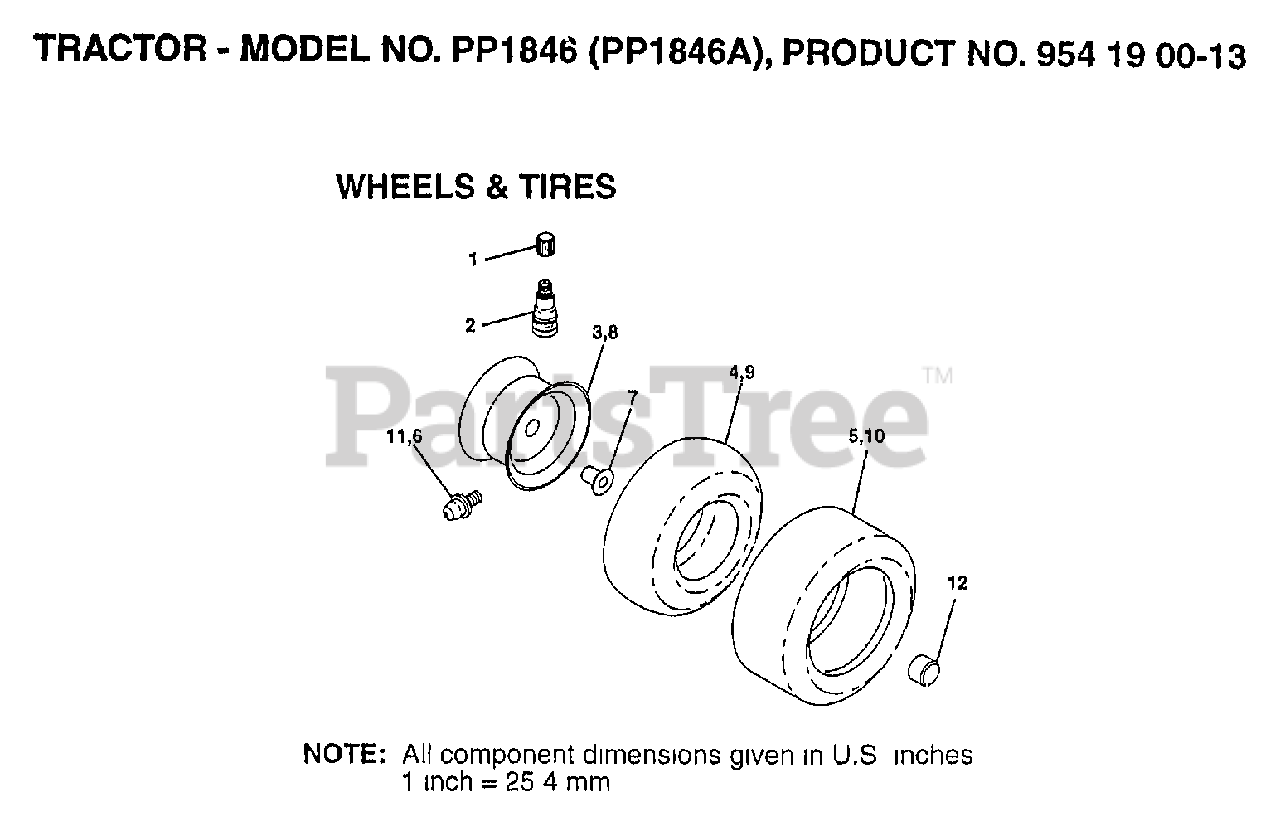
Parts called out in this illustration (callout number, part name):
1	VALVE CAP
2	VALVE STEM LT
3	RIM.FRONT.
4	TUBE.16X6.5/7.5-8
6	FITTING LT
7	"FLANGE, BEARING"
8	"WHEEL,REAR"
9	TUBE.23X8/10-12
11	ZERK FITTING M
